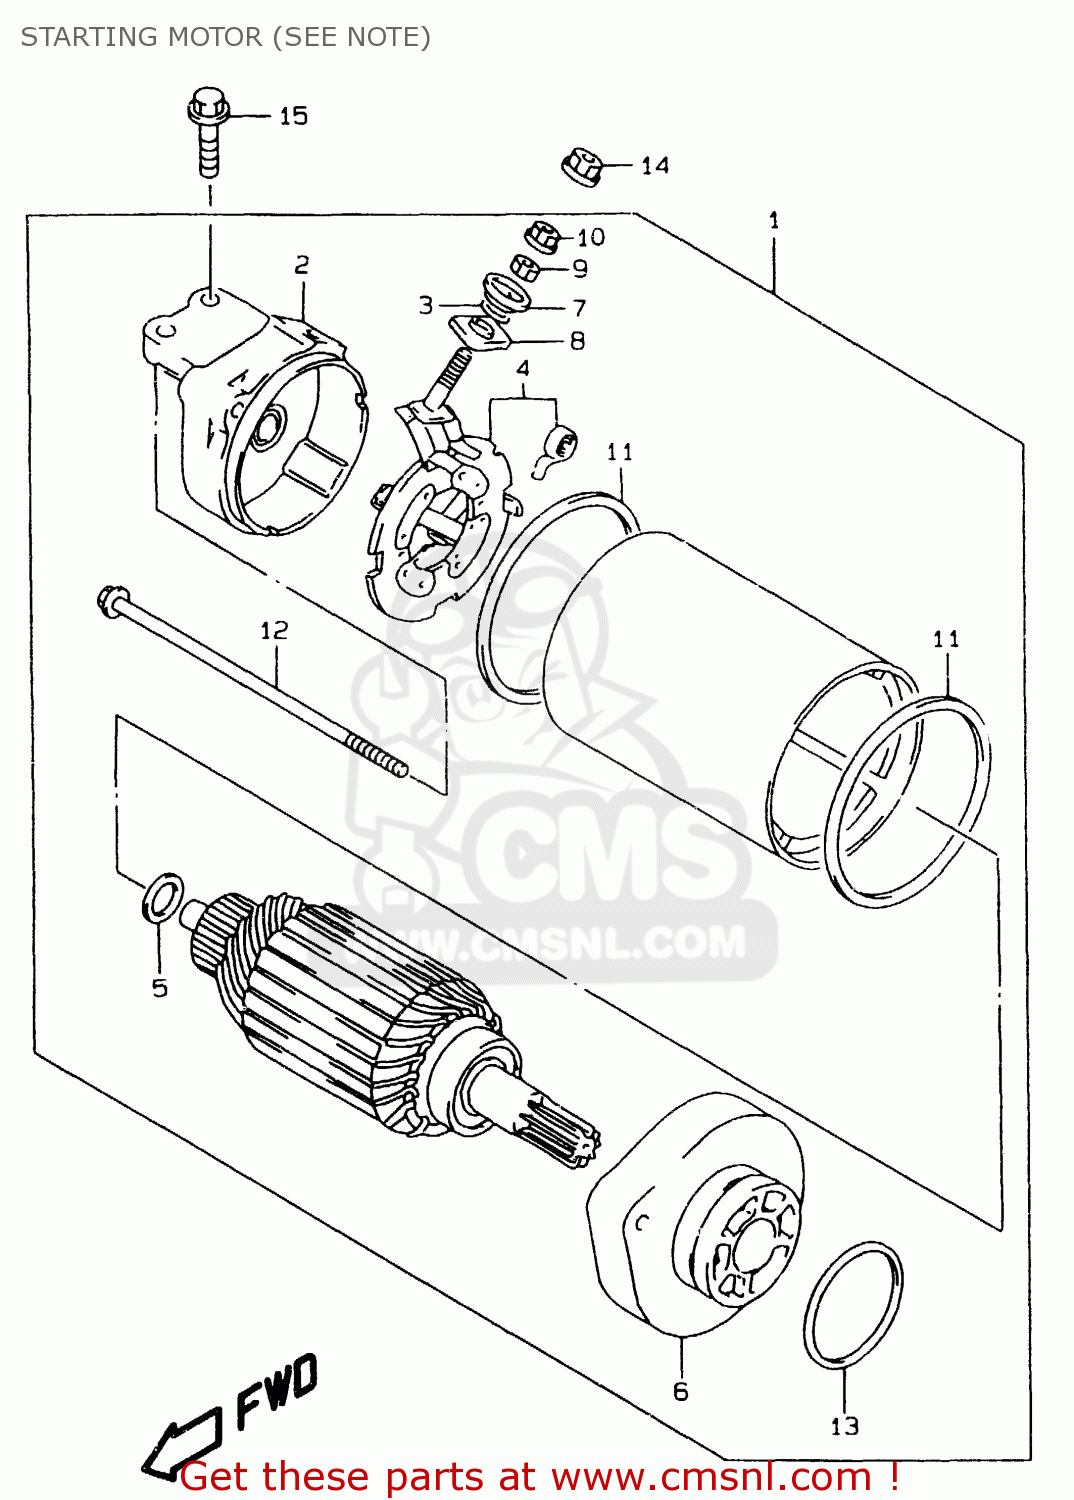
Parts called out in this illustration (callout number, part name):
1	MOTOR ASSY,STARTING
2	FRAME ASSY
3	O RING
4	HOLDER SET,BRUSH
5	SHIM SET,STARTING MOTOR
6	BRACKET SET
7	BUSHING
8	BUSHING
9	NUT
10	NUT
11	O RING
12	BOLT
13	O-RING (D:2.1 ID:34.7)
14	NUT
15	BOLT
